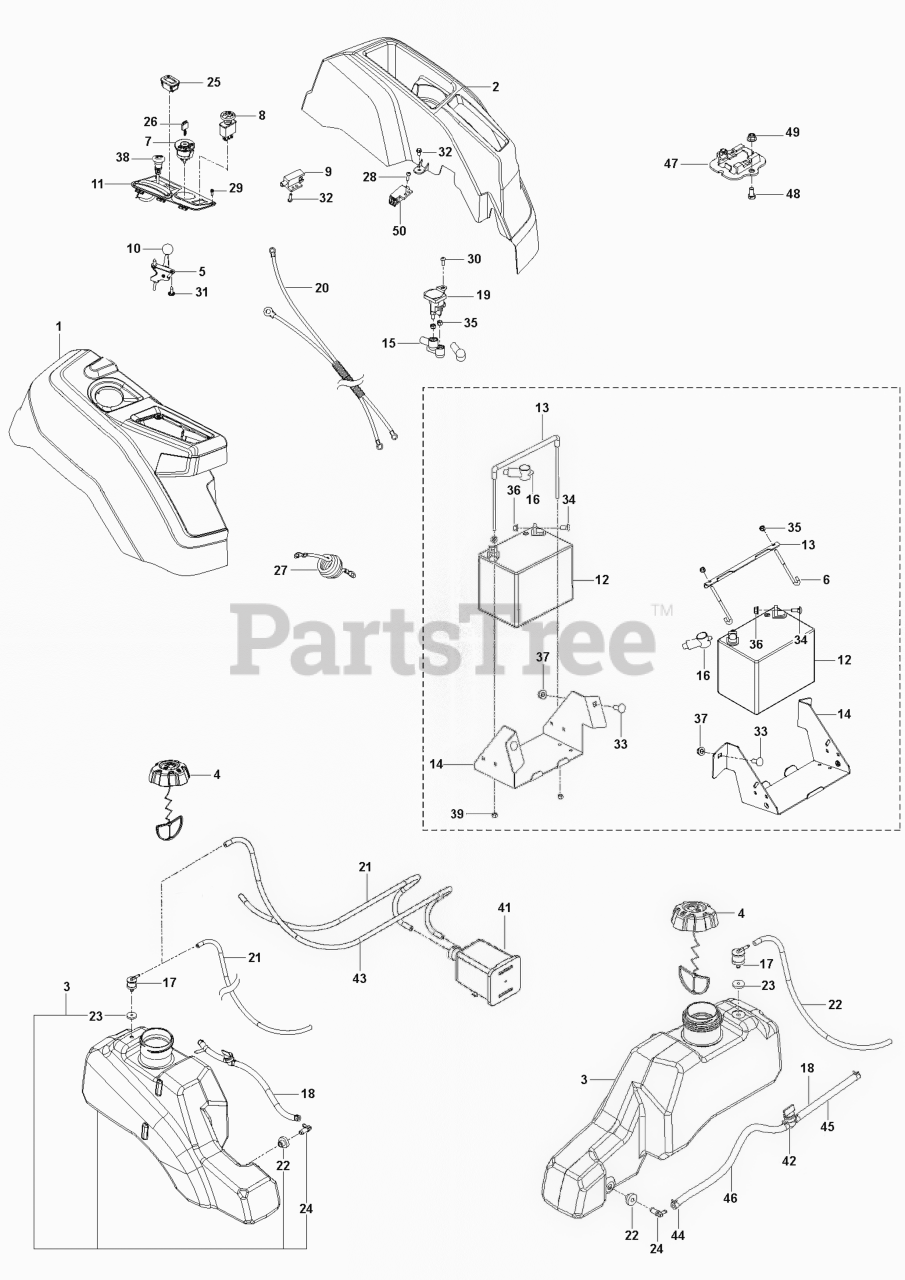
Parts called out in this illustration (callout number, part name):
1	CONSOLE.ASSY.RZ.REFRESH.RH
2	CONSOLE.LH.ASM
3	Tanks
4	CAP ASSY FUEL 3" GRAY
4	FUEL CAP
5	CABLE.THROTTLE.37"
5	THROTTLE CONTROL W/BALL KNOB
5	THROTTLE CABLE W/KNOB
6	HOOK.J.BATTERY
7	RP IGNITION SWITCH
8	RP SWITCH.PTO.TERMINAL.STD.RED
9	SWITCH.INTLK.RZ.RFRSH.BUTTON
10	KNOB.ROUND.BALL.BLACK
11	CONTROL.PANEL.RZ.REFRESH.RH
12	BATTERY, 12 V 300 AMP DRY
13	BATTERY TIE DOWN ASSEMBLY
13	BRACKET, BATTERY MOUNT
14	BOX BATTERY RZ BLACK
14	BOX.PNT.BATTERY.RZ.EDIP
15	TERMINAL COVER
17	VALVE.FUEL.CHECK
18	FUEL.HOSE.SHUT.OFF.ASM.10".3"
18	FUEL.HOSE.SHUT.OFF.ASM.10".18"
19	Solenoids
19	SOLENOID.STARTER.BRASS.PLUNGER
20	HARNESS.BTTRY.CABLE.RZ.REFRESH
21	HOSE.3/16".VAPOR.LINE.36"LGTH
21	HOSE.3/16".VAPOR.LINE.18"LGTH
21	HOSE.3/16".VAPOR.LINE.23"LGTH
21	HOSE.3/16".VAPOR.LINE.33"LGTH
21	HOSE.3/16".VAPOR.LINE.50"LGTH
22	BUSHING OUTLET T
23	GROMMET.ROV.SENTEC
24	STEM FUEL TANK
25	GUAGE.SRVCMNDR.HRMTR.
26	KEY MLD GEN DELTA
27	CABLE BATTERY POS RZ
28	SCREW.BUTTONHD.10-24X1/2.(2 2)
28	SCR #10-24 X .75 SKT HD BLK
29	SCREW 6-19X.437
30	SCR 1/4-20 X 5/8 BTN SKT HD ZD
31	SCREW.PAN.HEAD.#10
32	SCREW
33	RHSNB 3/8C X 1
34	RP BOLT 5/16-18 X3/4 ZN/YEL GR
35	NUT.1/4-20.HEX.NYLOC.ZD
36	5/16-18 NYLOC FLANGE NUT
37	NUT 3/8-16 HEX FLG NYLOC ZD
37	RHSNB 3/8C X 1
38	CHOKE.PUSH-IN.STYLE
39	LOCKNUT.NYLOC.1/4-20
41	CANNISTER, CARBON
42	FUEL VALVE
43	HOSE.3/16".VAPOR.LINE.23"LGTH
44	HOSE CLAMP
45	HOSE.1/4".LOW.PERM.FUEL.LN.10"
46	HOSE 1/4" LOW PERMEATION FUEL
47	BRACKET, CANISTER
48	HCS 5/16-18 X 5/8 GR 5 ZD
49	5/16-18 NYLOC FLANGE NUT
50	SWITCH.INTLK.RZ.RFRSH.BUTTON
